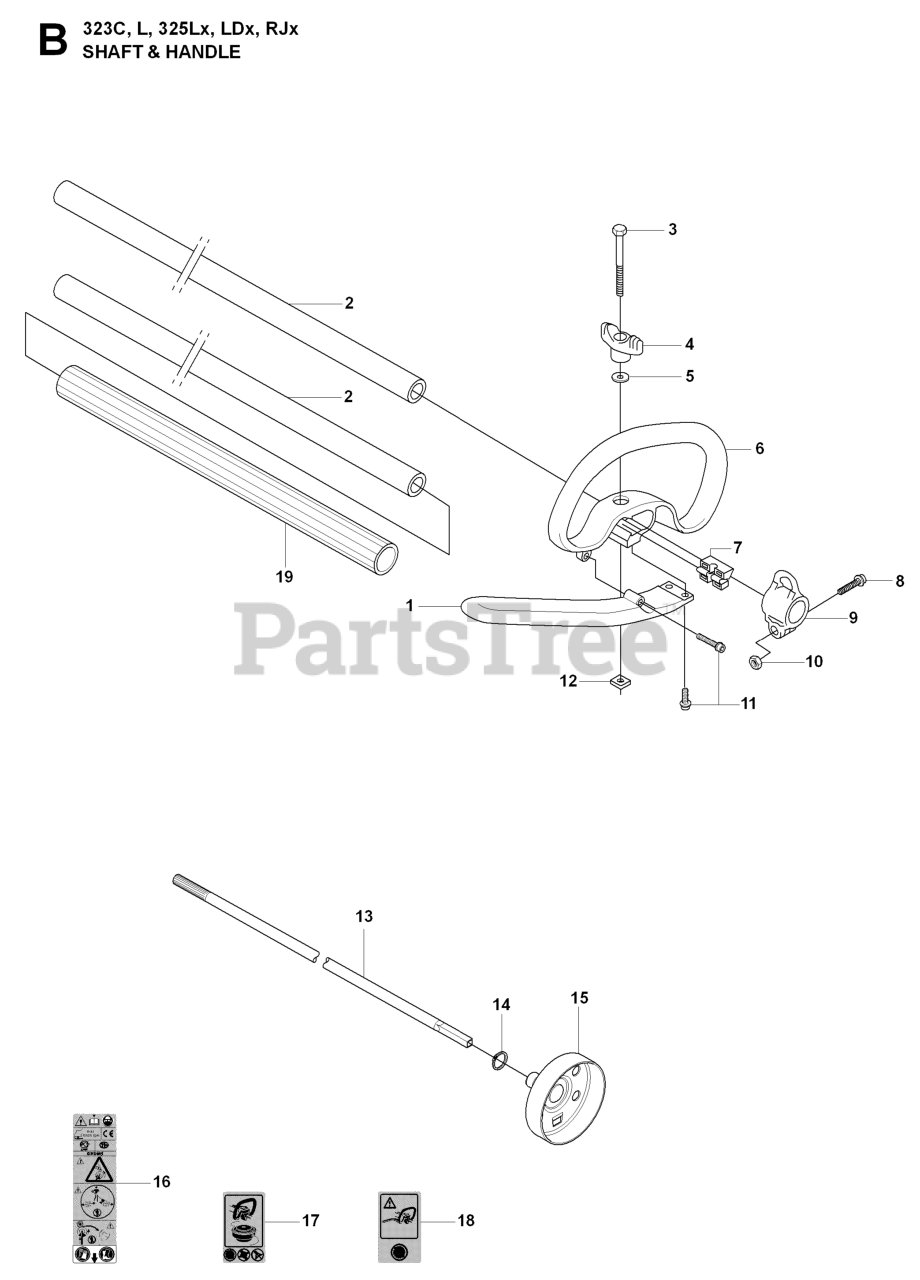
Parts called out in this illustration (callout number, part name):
1	HANDLE EXTENSION
2	TUBE DRIVESHAFT ASSY
2	DRIVE TUBE ASSEMBLY
3	SCREW M6X50
6	RP HANDLE, LOOP
6	HANDLE, LOOP
7	SPACER PLASTIC
8	SCREW
9	HARNESS HOLDER
13	DRIVE SHAFT
14	RETAINING RING SGA 10
15	CLUTCH DRUM
16	RP WARNING DECAL
17	DECAL WARNING "NO BLADES"
